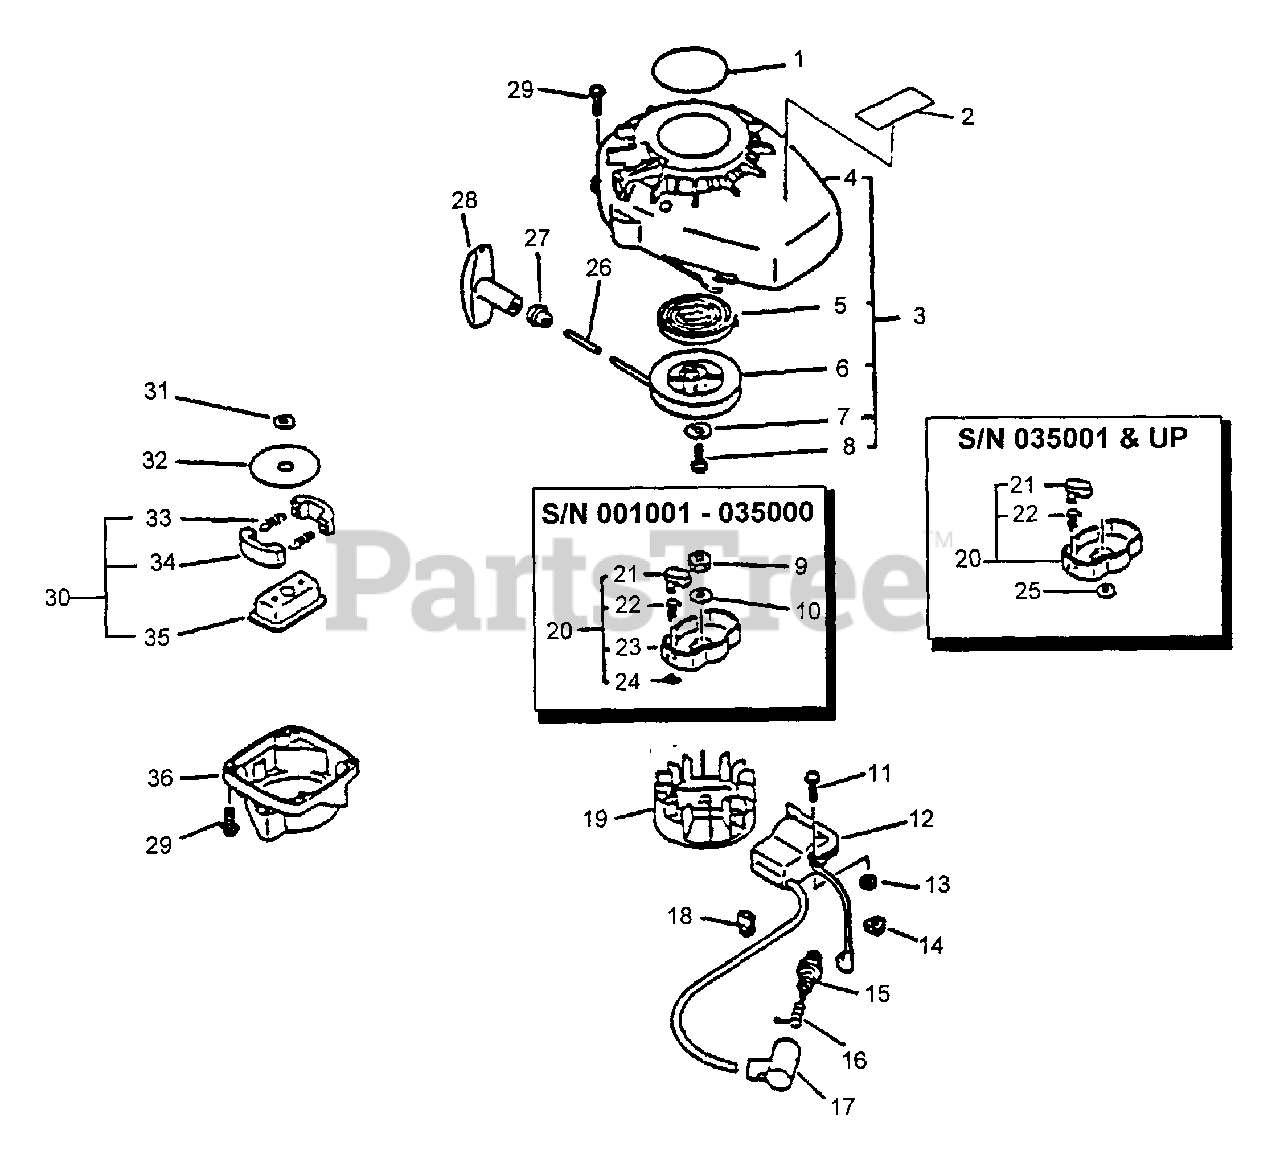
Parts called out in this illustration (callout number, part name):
1	LABEL - ECHO
1	LABEL - MODEL HC-1500
2	LABEL - MODEL
2	LABEL - CAUTION
3	STARTER ASSY
4	CASE, STARTER
5	SPRING, REWIND
6	REEL, ROPE
7	WASHER
9	NUT - 8
10	WASHER - 8
11	SCREW - 4X22
12	COIL, IGNITION
13	SPACER
15	SPARK PLUG -- BPM-6A
15	SPARK PLUG -- BPMR-6A
15	SPARK PLUG -- BPM-7Y
16	TERMINAL, SPARK PLUG CAP
17	CAP, SPARK PLUG
19	FLYWHEEL
20	STARTER PAWL ASSY
21	PAWL, STARTER
22	SPRING, RETURN
23	CATCHER, PAWL
24	RING, RETAINING - 4
25	LOCKWASHER - 8
26	ROPE, STARTER - 3X890
27	GUIDE, ROPE
28	GRIP, STARTER
29	SCREW - 4X16
30	CLUTCH ASSY
31	WASHER, CLUTCH
32	PLATE, CLUTCH
33	SPRING, CLUTCH
34	SHOE, CLUTCH
35	HUB, CLUTCH
36	CASE, CLUTCH
